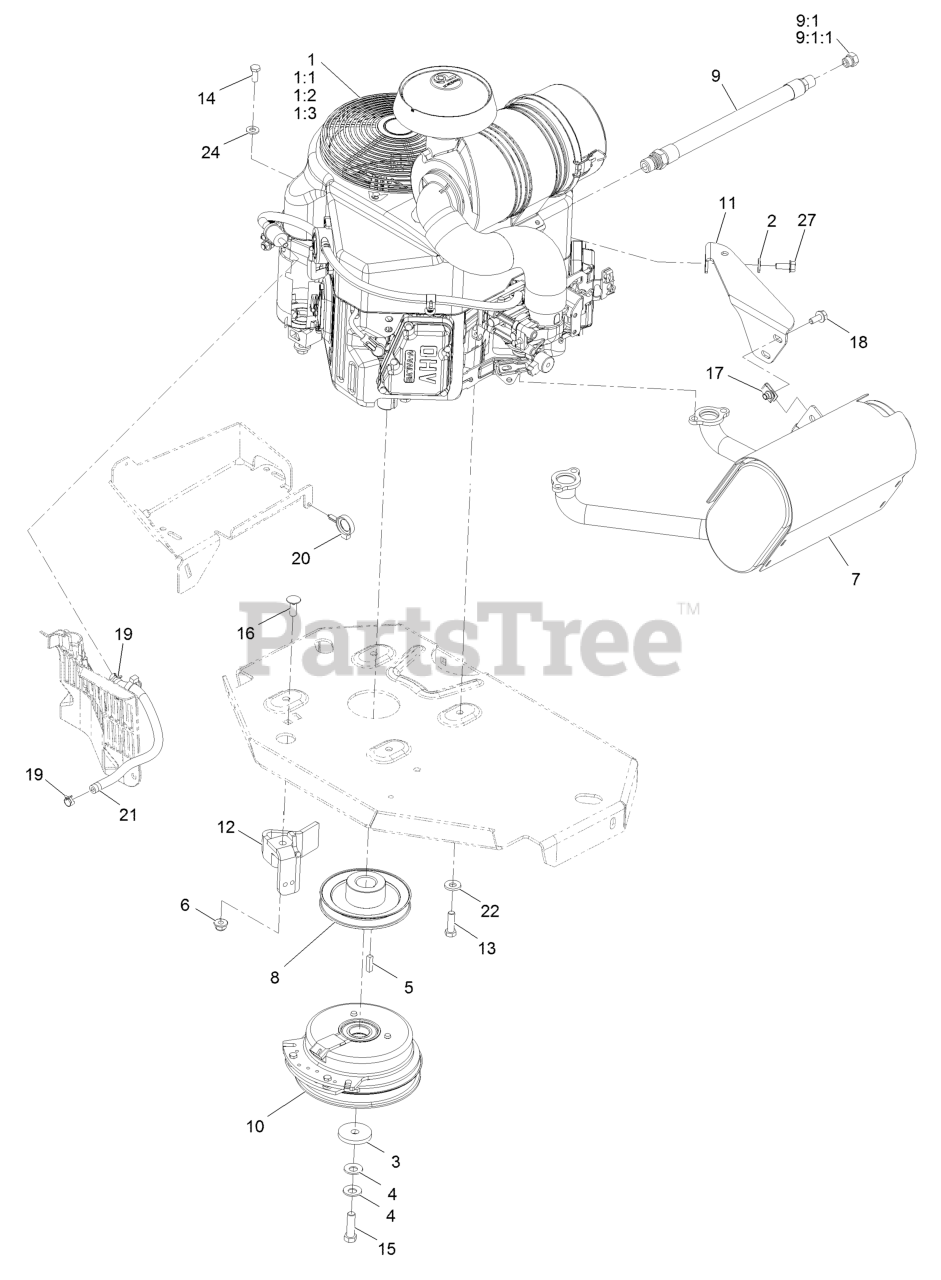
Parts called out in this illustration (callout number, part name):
1:1	Kawasaki 49065-7007 Engine Oil Filter
1:2	Kawasaki 11013-7044 Engine Air Filter
1:3	Kawasaki 11013-7045 Safety Filter
2	WASHER-SPRING
3	WASHER-CLUTCH
4	WASHER-SPRING
6	NUT-HF, NI
7	MUFFLER
8	SHEAVE-PUMP, DRIVE
9	ENGINE OIL DRAIN HOSE ASM
9:1	PLUG-HH
9:1:1	O-RING
10	CLUTCH KIT
11	BRACKET-MUFFLER
12	CLUTCH-ANCHOR
13	SCREW-HH
14	SCREW-HH
15	SCREW-HH 7/16-20 X 1 1/2 W/LOCTITE
16	SCREW-CARR
18	SCREW-HHF
19	CLAMP-HOSE
20	CLAMP-HOSE
21	HOSE-FUEL
22	WASHER-BELLEVILLE
24	WASHER-PLAIN
27	SCREW-HHF
